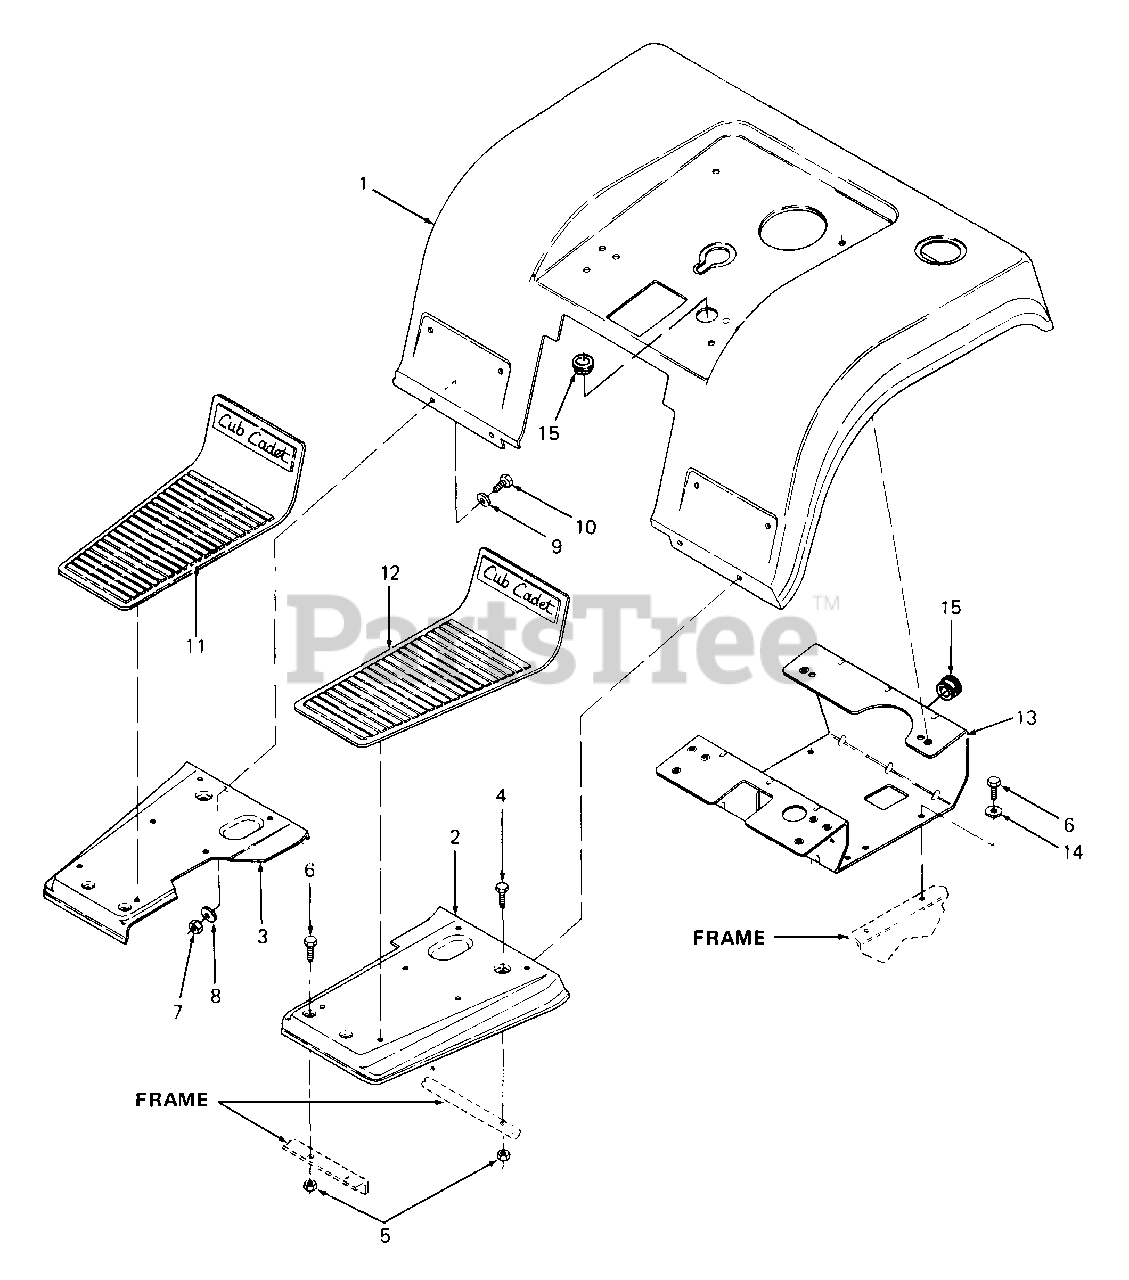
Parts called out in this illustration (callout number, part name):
5	Nut, Hex Center Lock, 5/16-18 GR5
6	Screw, Hex Cap, 5/16-18 x .62 Lg GR5
7	Nut, Hex Patch Lock, 1/4-20
8	Washer, Bell, .265 x .75 x .062 Thk
9	Washer, Flat, .281 x .73 x .063 Thk
10	Screw, Hex, Cap, 1/4-20 x .50 Lg GR5
11	Foot Pad - RH
12	Foot Pad - LH
14	Washer, Flat, .34 x .68 x .062 Thk
15	Bushing, Snap
